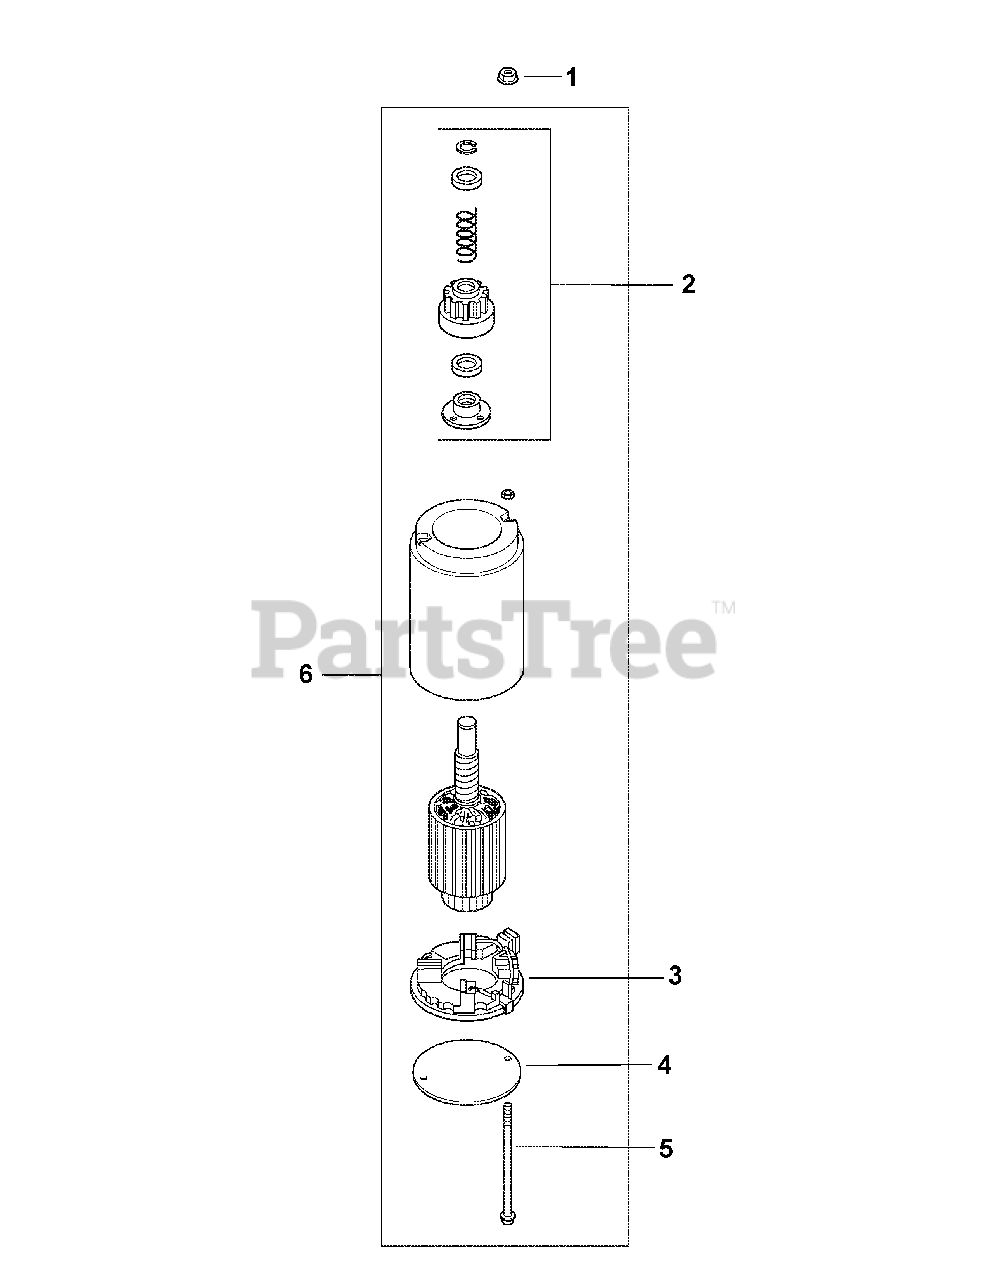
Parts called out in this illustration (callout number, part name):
1	Nut, Free Spinning Flg #10-24
2	Kit, Drive (J.E.)
4	Cap, Drive End (J.E.)
6	Starter Assembly
